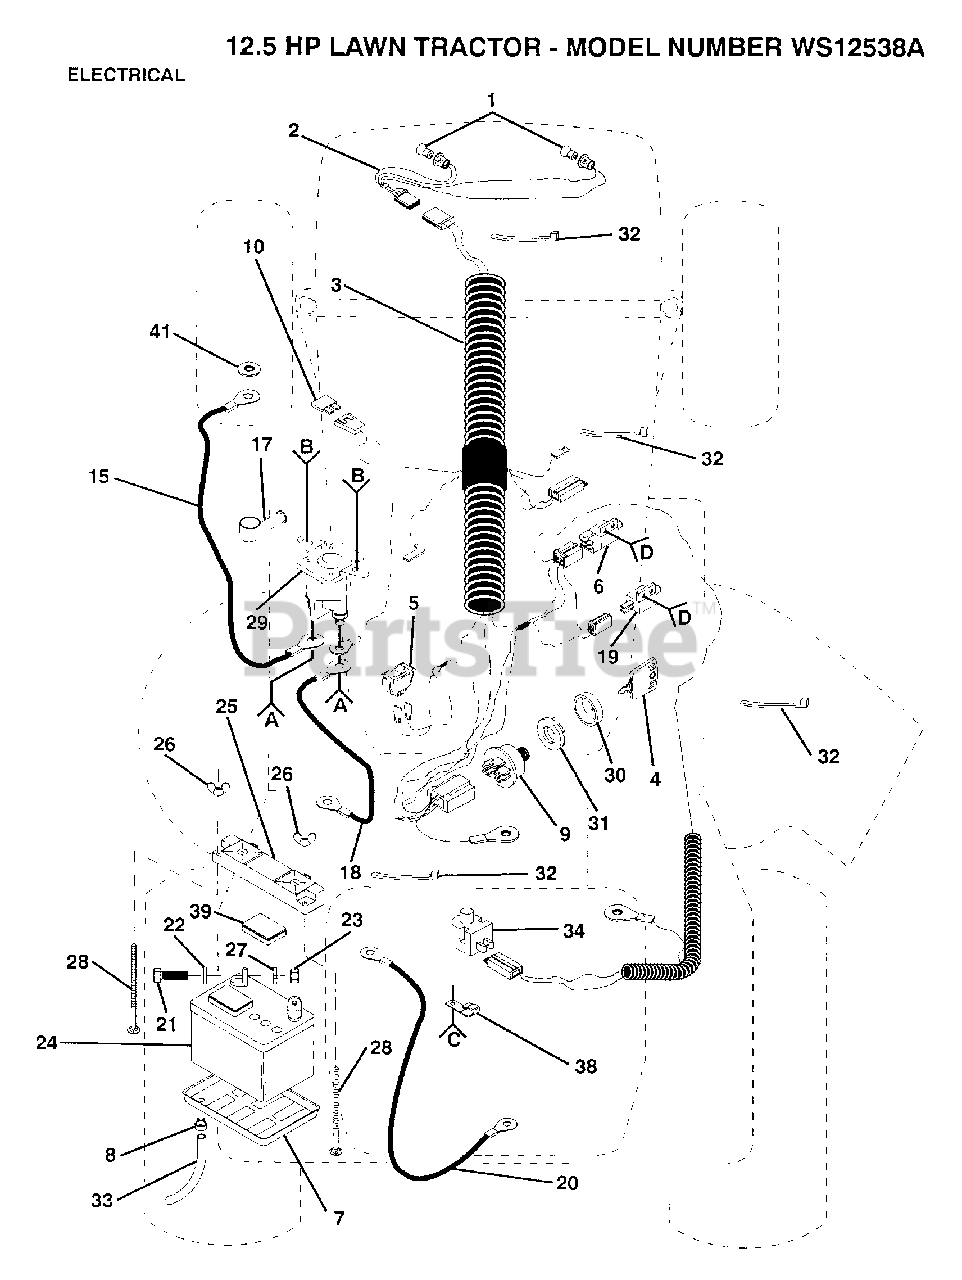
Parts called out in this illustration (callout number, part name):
2	HARNESS T
3	"HARNESS,WIRING"
4	KEY
5	SWITCH LT
6	SWITCH-INTER. GT
7	"TRAY T, BATTERY"
8	HOSE CLAMP T
10	FUSE HYT
15	CABLE T
18	STARTER CABLE GT
19	SWITCH INTERLOCKT
20	CABLE ASM.
21	BOLT LT
22	WASHER
27	LOCKWASHER
28	BOLT
32	WIRE TIE
34	SWITCH SEAT
39	"CAP,BATTERY "
